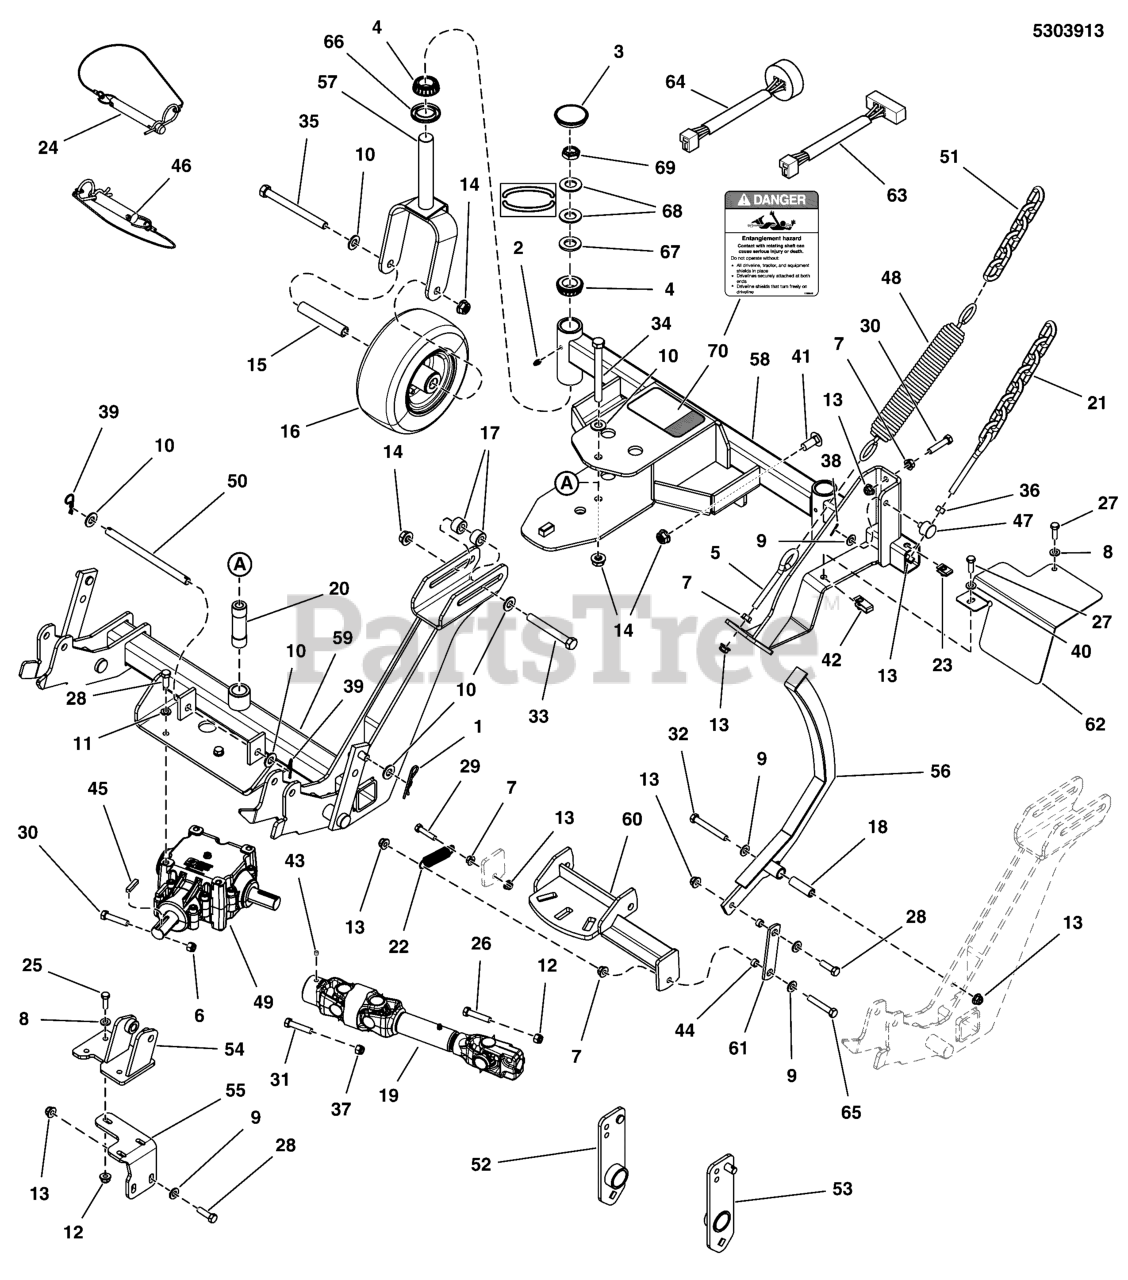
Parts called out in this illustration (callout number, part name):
1	CLIP-HAIRPIN
2	GREASE FITTING, 1/4-28 STR
3	CAP, GREASE, LOW PROFILE
4	BEARING, TAPERED ROLLER
5	EYE BOLT, 3/8-16 X 5, 2.88THRD, 1EYE, CZ
6	NUT, 3/8-16 HEX NYLON LOCK
7	NUT, 3/8-16 HEX LG. SERR FLG
8	WASHER, 5/16" SAE
9	WASHER, 3/8 SAE
10	WASHER, 1/2 SAE
11	WASHER, 3/8 LOCK
12	NUT, 5/16-18 HEX NYLOCK FLANGE
13	NUT, 3/8-16 HEX NYLOCK FLANGE
14	NUT, Hex Flange, Nylock, 1/2-13
15	AXEL, CASTER WHEEL
16	TIRE ASSM, 9 X 3.5 - 4, FF, CASTER
17	SPACER, .52 X 1.00 X .63 YZ
18	SPACER, .39 X .63 X 1.94
19	DRIVE SHAFT, BROOMHEAD
20	SPACER, .52 X .99 X 3.50
21	HANGER, BROOM - 8LINK
22	SPRING-EXTN 1.040ODX 04.000LG .105WIRE D
23	BODY CLIP, 5/16-18-7GA MATERIAL
24	HITCH PIN ASSY., 1/2 X 3.50
25	BOLT, 5/16-18 X 1-1/4" GD5
26	BOLT, 5/16-18 X 1-3/4 GD5 CZ
27	BOLT, 5/16-18 X 1" GD5
28	BOLT, 3/8-16 X 1-1/4" GD5 CZ
29	BOLT, 3/8-16 X 1-1/2" GD5 CZ
30	BOLT, 3/8-16 X 1-3/4" GD5 CZ
31	SOC HD CAP SCREW, 3/8-24 X 3"
32	BOLT, 3/8-16 X 3" GD5 CZ
33	BOLT, 1/2-13 X 4" GD5 CZ
34	BOLT, 1/2-13 X 5" GD5
35	BOLT, 1/2-13 X 6" GD5
36	NUT, 3/8-16 HEX
37	NUT, 3/8-24 HEX NYLON LOCK
38	PIN, 3/32 X 0.750, COT, ZINC/CLEAR
39	PIN, HAIR, .0915 X 1-7/8
40	WASHER, 5/16 F436 FLAT
42	BODY CLIP, 5/16-18 -1/4 MATERIAL
43	SET SCREW, 3/8-16 X 1/2 KNURLED
44	SPACER, .38 X .50 X .27, CZ
45	KEY, 1/4 SQ. X 1-1/4
46	HITCH PIN ASSEMBLY, 1/2" X 2.50"
47	ADJUSTER, BRAKE LINKAGE
48	SPRING, EXT, 1.5ODX12.25X.234WIRE BLK
49	GEARBOX, SUPERIOR, 3:1
50	ROD, LATCH PIVOT, BROOM
51	CHAIN, PEERLESS, 4/0 STRAIGHT COIL, 6-LINK
52	WELD., SPRING PVT, SNOW, LH
53	WELD., SPRING PVT, SNOW, RH
54	WELD., ACTUATOR MOUNT
55	PLATE, ACTUATOR MNT. SUPPORT
56	WELD, BROOM, FOOT PEDAL, S800X
57	WELD, CASTER YOKE
58	WELD, MOUNT, BROOM
59	WELD, MAIN FRAME, BROOM
60	WELD, ANGLE LOCK
61	BAR, FOOT PEDAL LINK
62	GUARD, DRIVESHAFT, INNER
63	WIRE HARNESS, BROOM,S800,RECT CONN
64	WIRE HARNESS, BROOM, S800X, ROUND CONN
65	BOLT, 3/8-16 X 1-3/4 GD5 TFL
66	SEAL, GREASE
67	WASHER, 3/4 SAE
68	WASHER, BELLEVILLE - 1.500 X .755
69	NUT, 3/4-16 HEX JAM NYLON LOCK
70	DANGER DECAL, ENTANGLEMENT HAZARD
